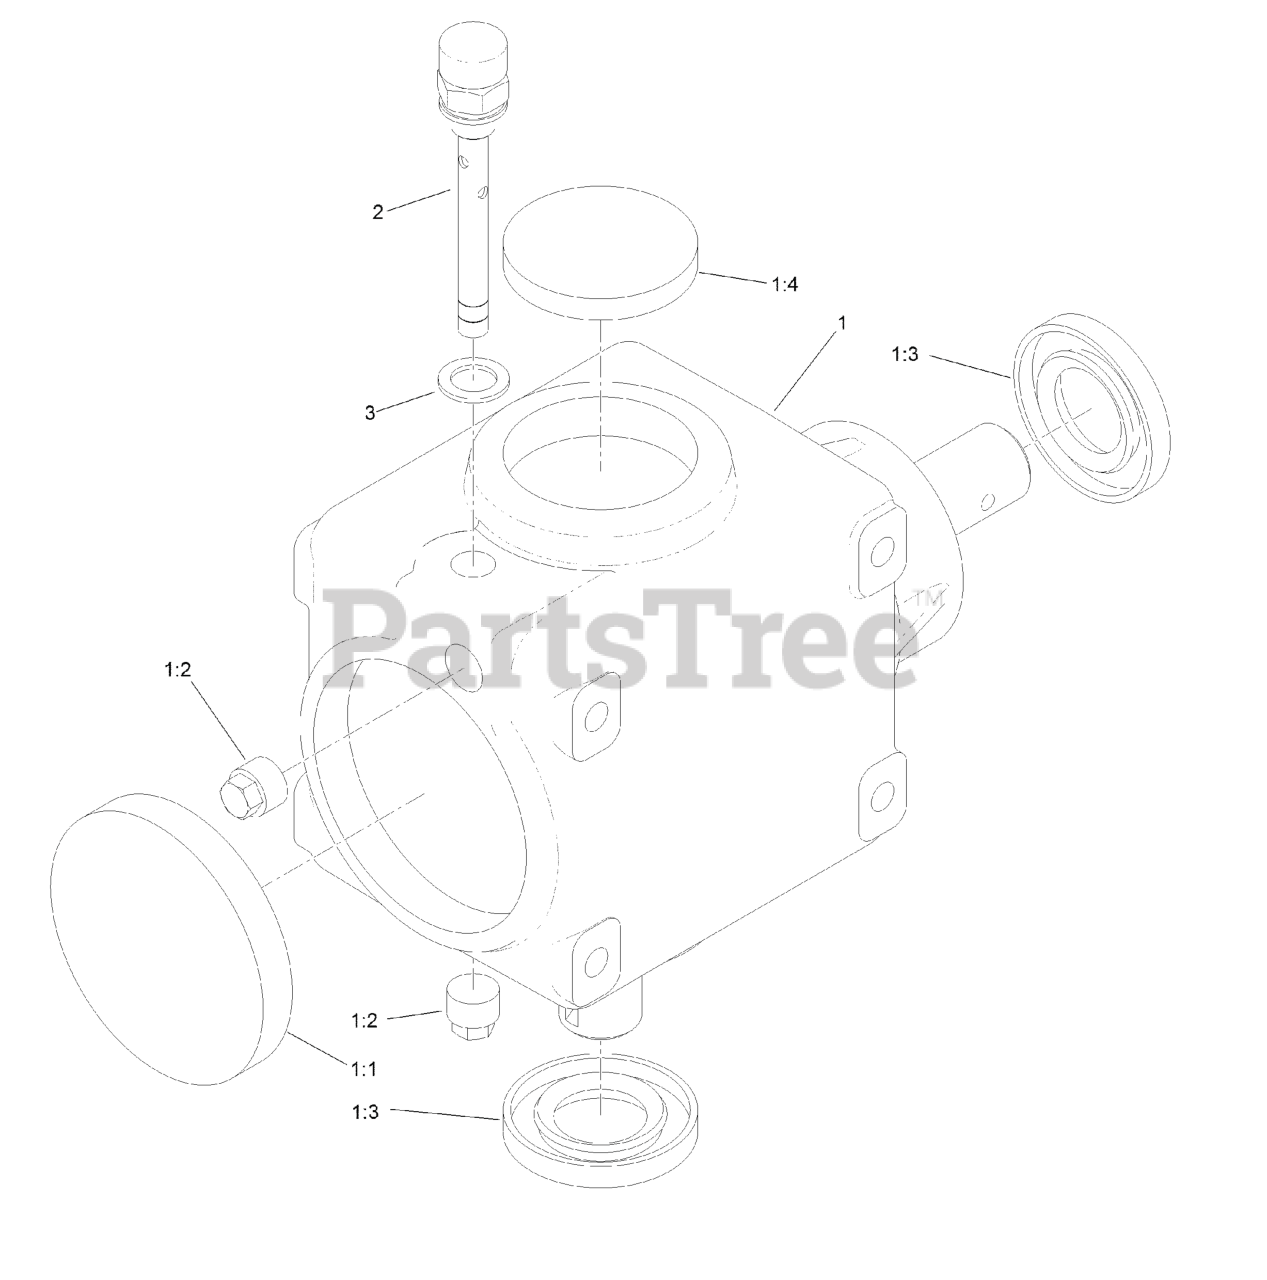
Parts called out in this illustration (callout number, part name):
1	Gearbox ASM
1:1	CAP-OIL
1:4	CAP-OIL
2	PLUG-BREATHER
